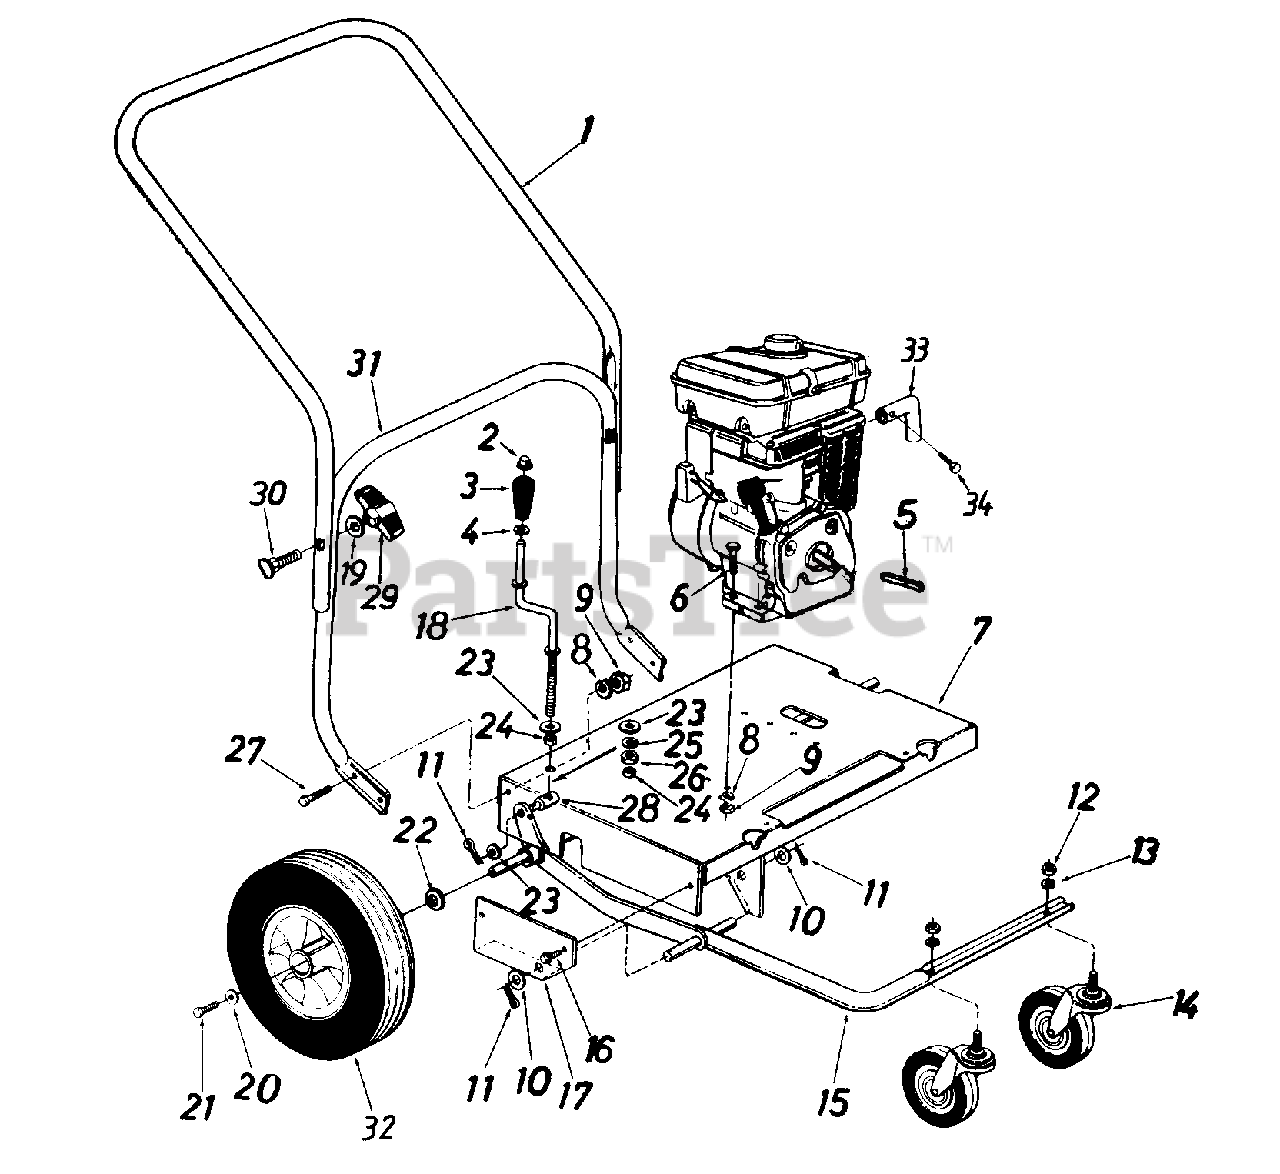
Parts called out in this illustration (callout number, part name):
2	Push Nut 3/8" Rod
3	Crank Knob
4	Fl-Wash. .385" I.D. x .62"
5	Sq. Key 1/4" x 2.0" Lg.
6	Hex Bolt 5/16-18 x 1.50" Lg.
9	Hex Nut 5/16-18 Thd.
10	Fl-Wash. .63" I.D. x 1.25"
11	Cotter Pin 1/8" Dia. x 1.0"
12	Hex Nut 1/2-13 Thd.
13	L-Wash. 1/2" I.D.
14	Swivel Caster Wheel 5" Dia. x 1.25"
19	Saddle Wash. .32" I.D. x .93"
20	Fl-Wash. .34" I.D. x .87" O.D.
21	Hex L-Bolt 5/16-24 x .64" Lg.
22	Fl-Wash.
23	Fl-Wash. .38" I.D. x .57"
24	Spacer .382" I.D. x .50" x .180" Lg.
25	L-Wash. 3/8" I.D.
26	Hex Nut 3/8-8 Thd.
27	Hex Bolt 5/16-18 x .75" Lg.
28	Ferrule
29	Hand Knob
30	Carriage Bolt 5/16-18 x 2.0"
33	Outlet Pipe
34	Hex Wash. Hd. AB-Tap Scr. #8 x .5" Lg.
